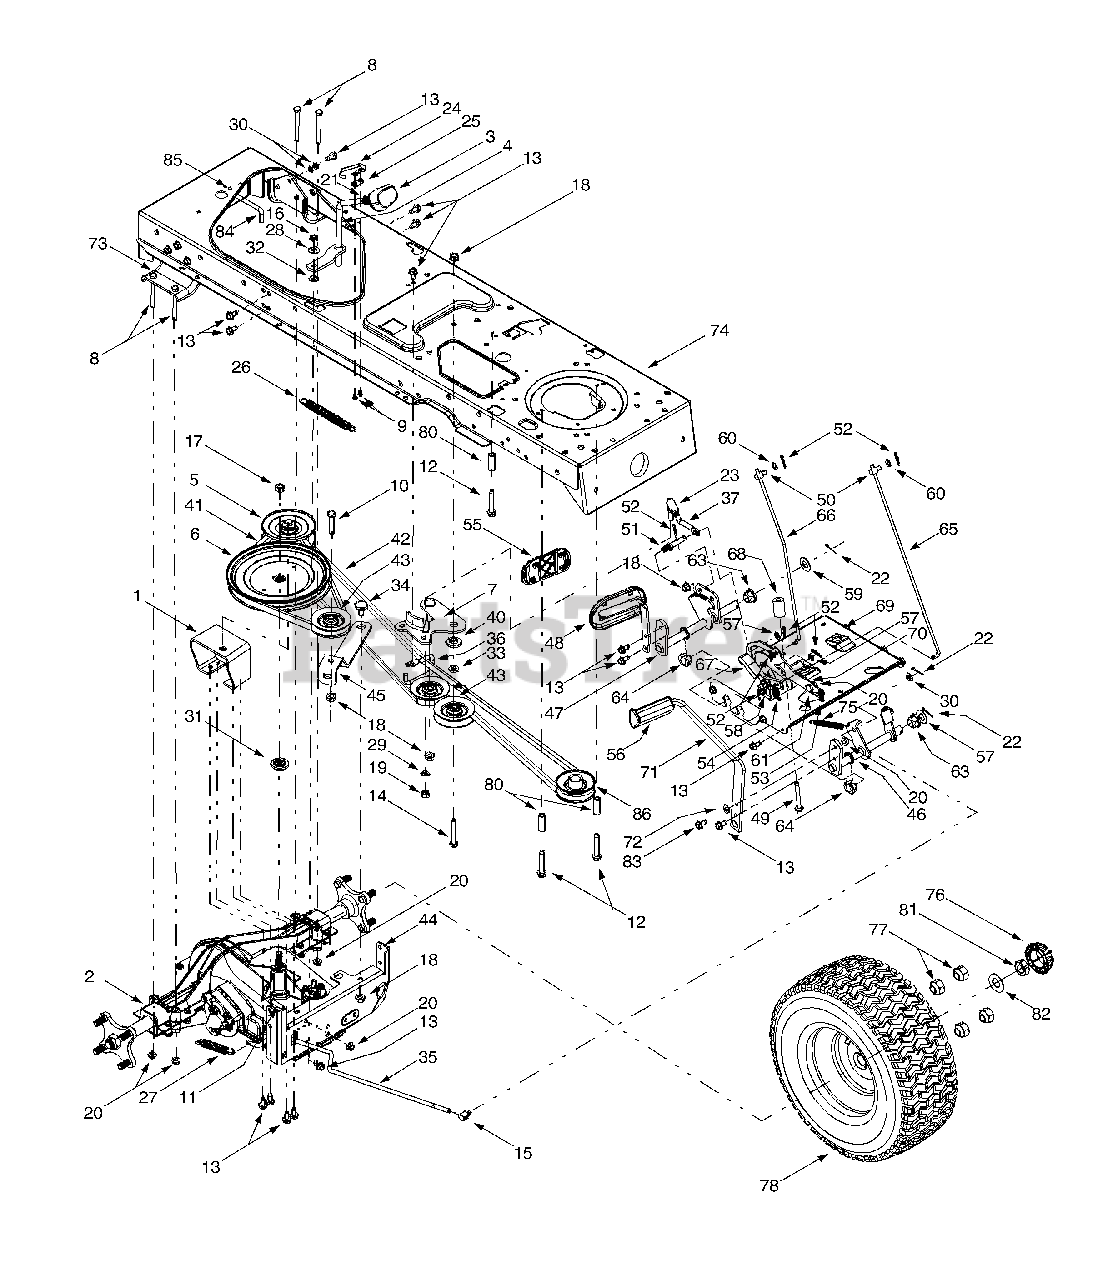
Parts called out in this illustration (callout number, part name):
1	Variable-speed Bracket Assembly
2	Two-speed Transmission Assembly
3	Shfter Knob
4	Shift Lever
5	Variable-speed Pulley Assembly
6	Transmission Pulley, 8.5
7	Double-idler Bracket
8	Hex Cap Screw, 5/16-18 x 2.75
9	Self Tapping Screw, #8-18 x .5
10	Hex Cap Screw, 3/8-16 x 1.75
11	Hex Cap Screw, 5/16-18 x 1.5
12	Self-tapping Screw, 1/4-20 x 1.25
13	Self Tapping Screw, 5/16-18 x .625
14	Hex Cap Screw, 3/8-16 x 2.25
15	Ferrule, 5/16 x .312 Dia.
16	Hex Jam Nut, 3/8-16
17	Hex Flange Nut, 7/16-20
18	Flange Lock Nut, 3/8-16
19	Hex Nut, 3/8-16
20	Flange Lock Nut, 5/16-18
21	Hex Jam Nut, 3/8-16
22	Cotter Pin
23	Ball Joint, 3/8-24
24	Spring Switch
25	Insulator Nut Plate
26	Extension Spring, .62 Dia. x 6.12
27	Extension Spring, .59 OD x 4.0
28	Bell Washer, .401 x .870 x .063
29	Lock Washer, 3/8
30	Flat Washer, 5/16
31	Pulley Hub, 1/2 Spline
32	Flat Washer, .44 x .75 x .06
33	Flat Washer, .407 x .812 x .135
34	Shoulder Screw, .625 Dia. x .21
35	Brake Rod
36	Belt Guard
37	Idler Adjustment Rod, 3/8
38	Self-tapping Screw, 1/4-20 x 1.75
39	Transmission Belt Guard Rod
40	Shoulder Spacer, .380 ID
41	Variable-speed Belt
42	Drive Belt
43	Flat Idler, 2.75 OD
44	Transmission Torque Bracket
45	Idler Bracket
46	Brake Control Shaft Assembly
47	Speed Control Shaft Assembly
48	Drive Pedal Assembly
49	Self Tapping Screw, 5/16-18 x 2.5
50	Ferrule, 1/4-20
51	Pin, 3/8-16 x 2.43
52	Cotter Pin
53	Compression Spring, .34 OD x 1.0
54	Extension Spring, .5 OD x 1.41
55	Drive Pedal Pad
56	Brake Pedal Pad
57	Flat Washer, .281 x .5 x .0625
58	Flat Washer, 9/32 x 1/2 x 1/16
59	Flat Washer, .64 x 1.24 x .06
60	Flat Washer, .344 x .062 x .03
61	Shoulder Screw, .437 x 1.62
62	Shoulder Screw, .5 x .434
63	Hex Flange Bearing
64	Split Hex Flange Bearing
65	Cruise Control Rod
66	Brake Lock Control Rod
67	Cruise Latch
68	Spacer, 5/16 x 1.54
69	Steering Support Bracket
70	Drive Lockout Bracket
76	Hub Cap
77	Lug Nut, 7/16-14
78	Wheel Assembly Complete, 23 x 10.5 x 12
78	Rim Only 12.0X7.0
78	Air Valve
79	Split Spacer, .25 x .37 x 1.32
80	Spacer, .372 x .26 x 1.03
81	Jam Nut, 3/4-16
82	Flat Washer, .78 x 1.59 x .06
83	Hex Screw, 5/16-18 x .75
84	Transmission Belt Guard Rod
85	Self Tapping Screw,1/4-20 x .5
86	Engine Pulley, 3.56"
